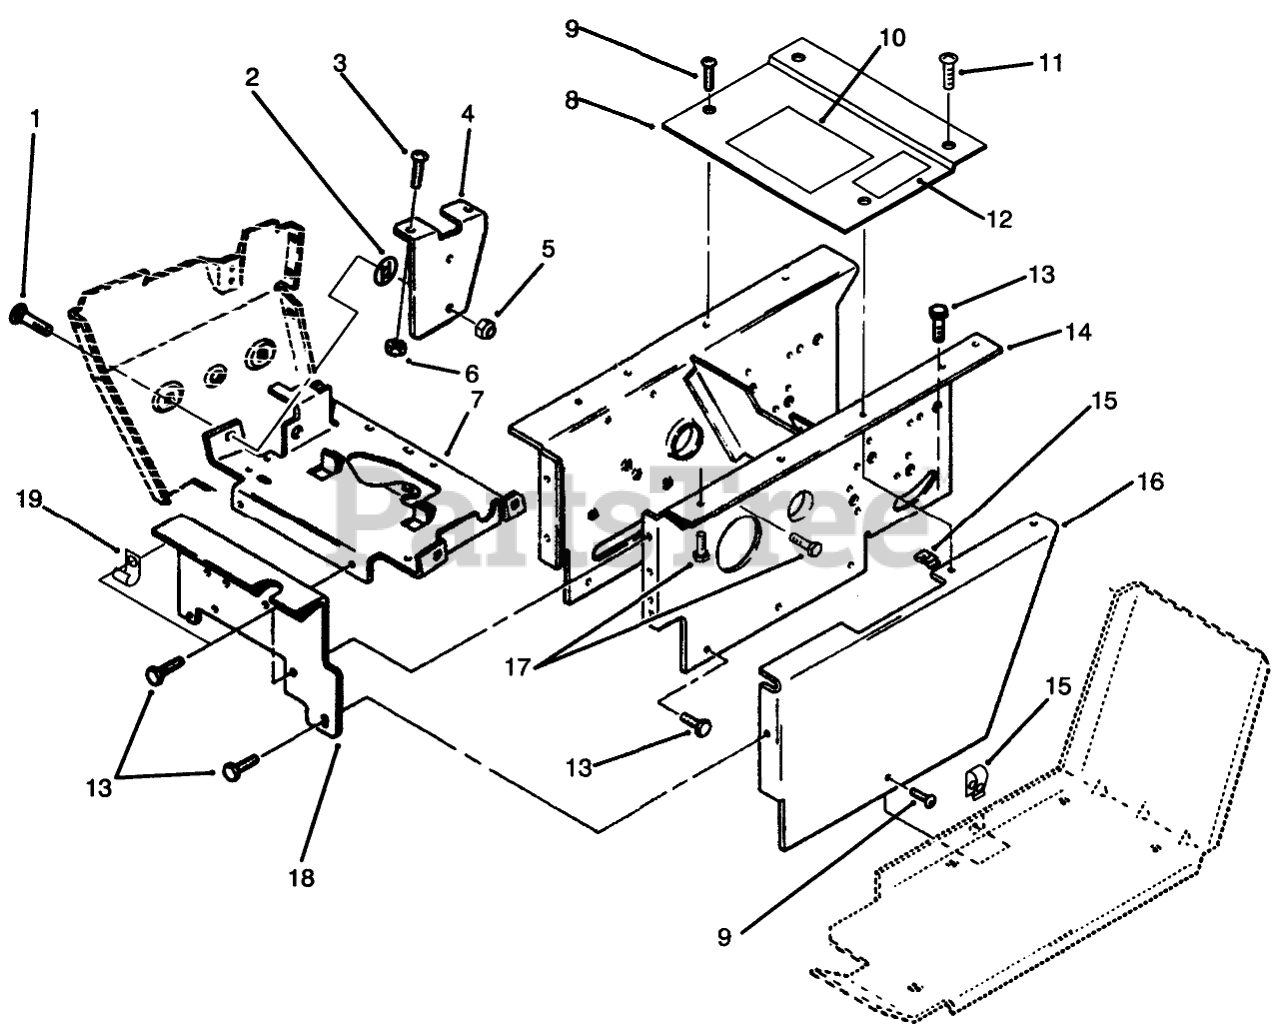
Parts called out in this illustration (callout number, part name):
1	BOLT-CARR
2	NUT-PUSH
3	SCREW-HH
4	Bracket-Holder
5	NUT-LOCK, NI
6	Nut
7	WLD-SUPPORTB
8	Plate-Hoodstand, Top (Incl. Ref. #10)
9	SCREW-PPH
10	DECAL-DANGER
11	SCREW 1/4-20X.87
12	DECAL-PARKING BRAKE
13	Bolt
14	Hoodstand
16	Cover-Side LH
17	SCREW-HH
18	Plate-Front
19	CLIP
